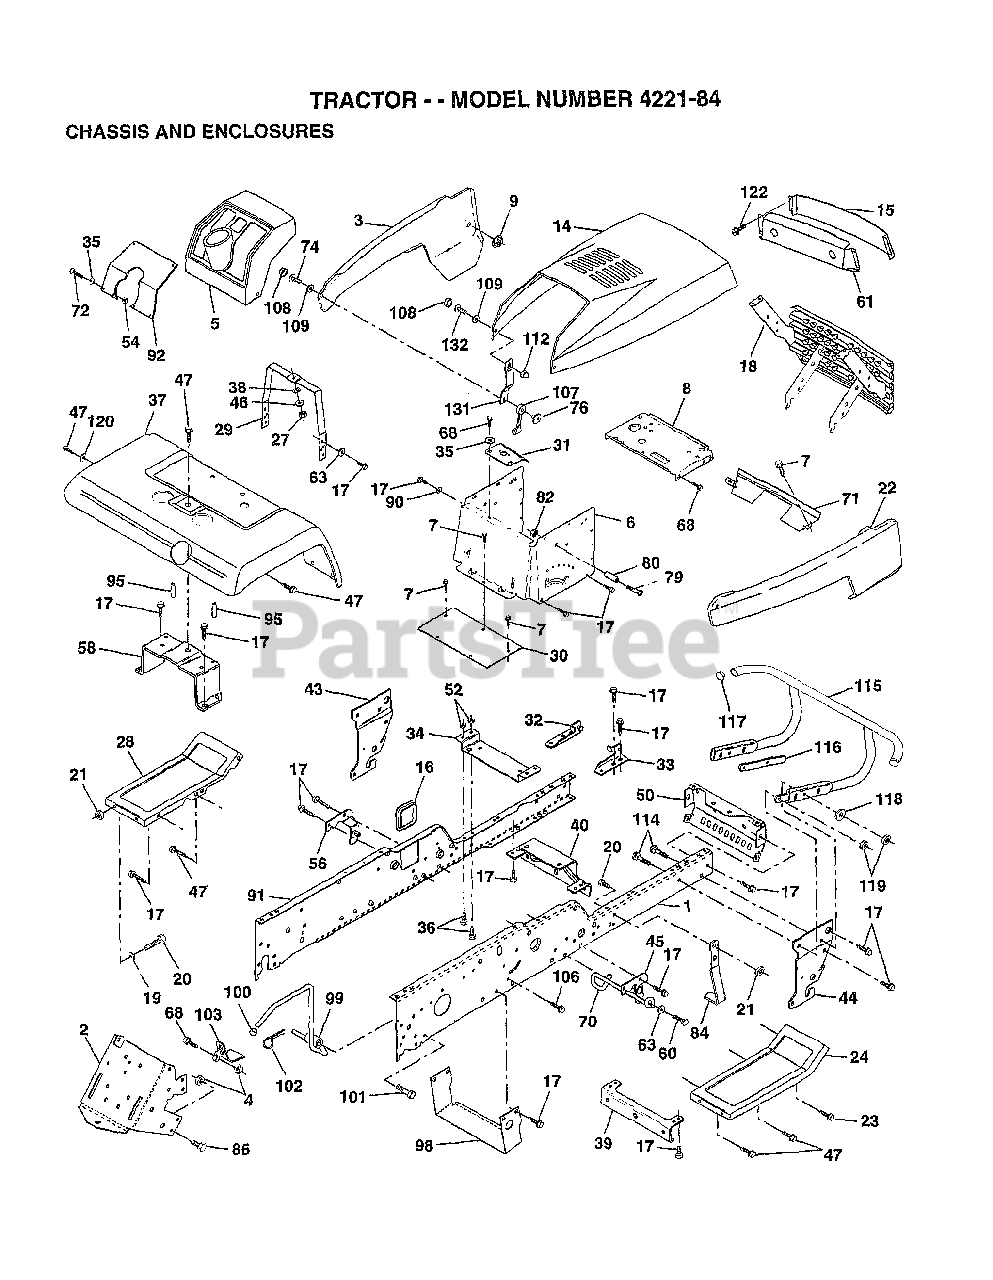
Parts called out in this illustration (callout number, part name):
1	"RAIL,FRAME RH"
2	DRAWBAR GT
3	PANEL ASM SIDE LH
4	NUT.7/16
5	DASHBOARD BLACK
6	DASH LOWER
7	SCREW
8	SUPPORT.DASH.BTRY
9	PAL NUT LT
15	LENS.BAR.CLEAR
16	COVER ACCESS
17	SCREW
19	WASHER
20	BOLT
22	PANEL ASM SIDE RH
23	SCREW GTV
24	FOOTREST.RH.LT/GT
28	FOOTREST.LH.LT/GT
29	DASH.SUPT.YP/HUSQ
30	SADDLE.HYDRO.95
31	BRKT SUPT 1-PC VG
32	BRACKET ASM FRAME
33	BRACKET ASM FRAME
34	BRACKET.ENG.SUPT.
35	WASHER
36	BOLT
38	LOCKWASHER
39	BRACKET.AXLE.FRT.
40	"BRKT SUPPORT,AXLE"
43	BRACKET.SUS.FT.LH
44	BRACKET.SUS.FT.RH
45	BRACKET ASM., SUSP CHASSIS RH
46	WASHER PM
47	SCREW LT
50	"BRKT CHASSIS,FRNT"
56	BRACKET ASM., SUSP CHASSIS LH
58	BRKT.ASM.FENDER
60	SCREW
61	BEZEL.ASM.
63	WASHER
70	GUIDE.BELT.MID.SP
71	STRAP.GRILLE.424
72	SCREW
74	SCREW
76	WELDNUT
79	SCREW
80	SPACER LT
84	STOP.OVER.CENTER
86	BOLT
90	LOCKWASHER
91	"RAIL FRAME,LH"
92	"PLATE-DASH,SLKSCR"
95	NUT-PUSH YT
98	BRACKET SKID CHAS
99	ROD BYPASS
101	SCREW LT
103	LOCK BYPASS BRKT
107	HOOD LATCH T
108	SNAP CAP LT
109	WASHER LT
112	ACORN NUT RB
114	BOLT.3/8-14X1.25
115	BUMPER.ASM
116	BRACKET.EXT.BUMP.
117	PLUG.PLASTIC
118	WASHER
120	WASHER HYT
122	SCREW.HEX.WS.HD
131	BKT.SPT.HOOD/PANL
132	SCREW.10-24X3/8.
